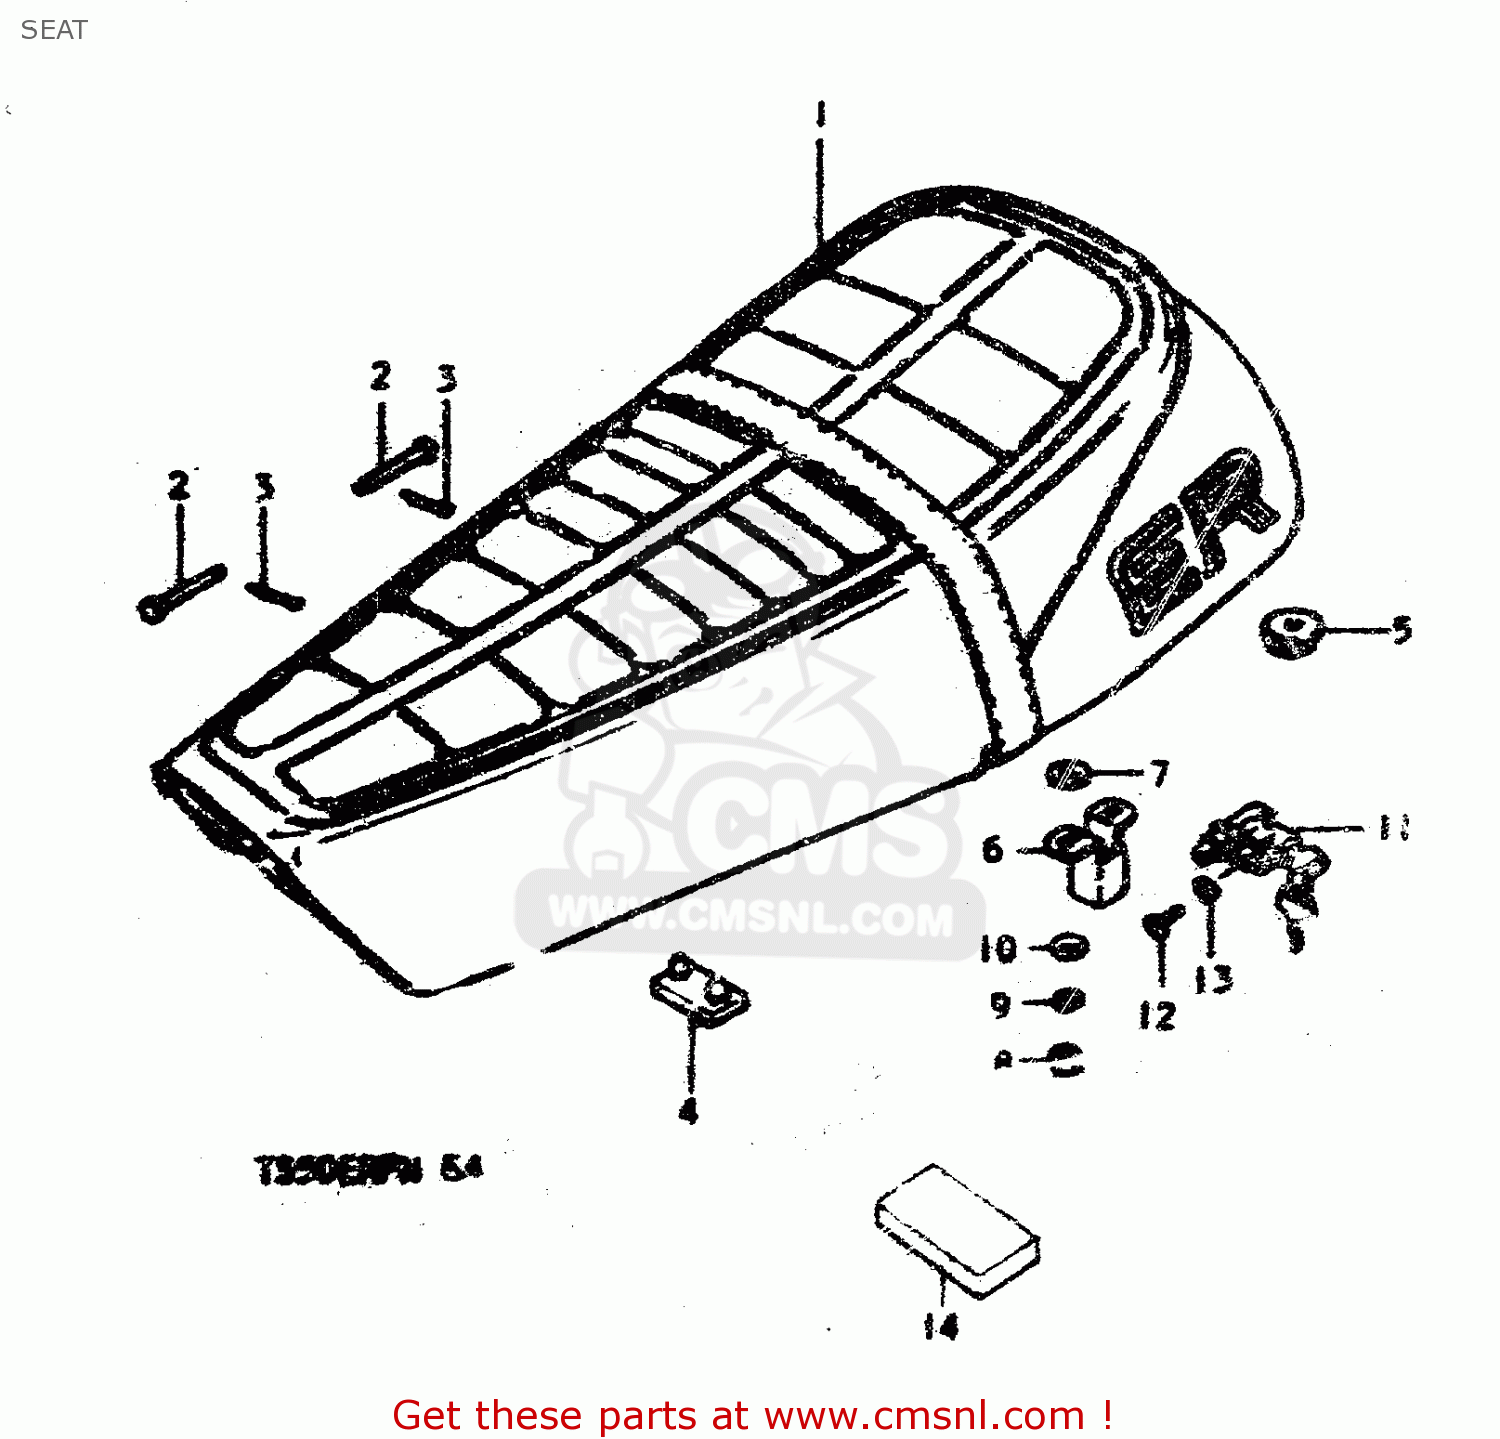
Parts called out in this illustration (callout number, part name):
1	SEAT ASSY (BLACK)
2	PIN
3	PIN
4	CUSHION
5	CUSHION
6	PLATE,CLAMP GUIDE
7	WASHER(8.5X18X1)
8	NUT
9	LOCK WASHER
10	WASHER
11	LOCK ASSY,SEAT
12	SCREW
13	LOCK WASHER
14	CUSHION(30X60X10)
